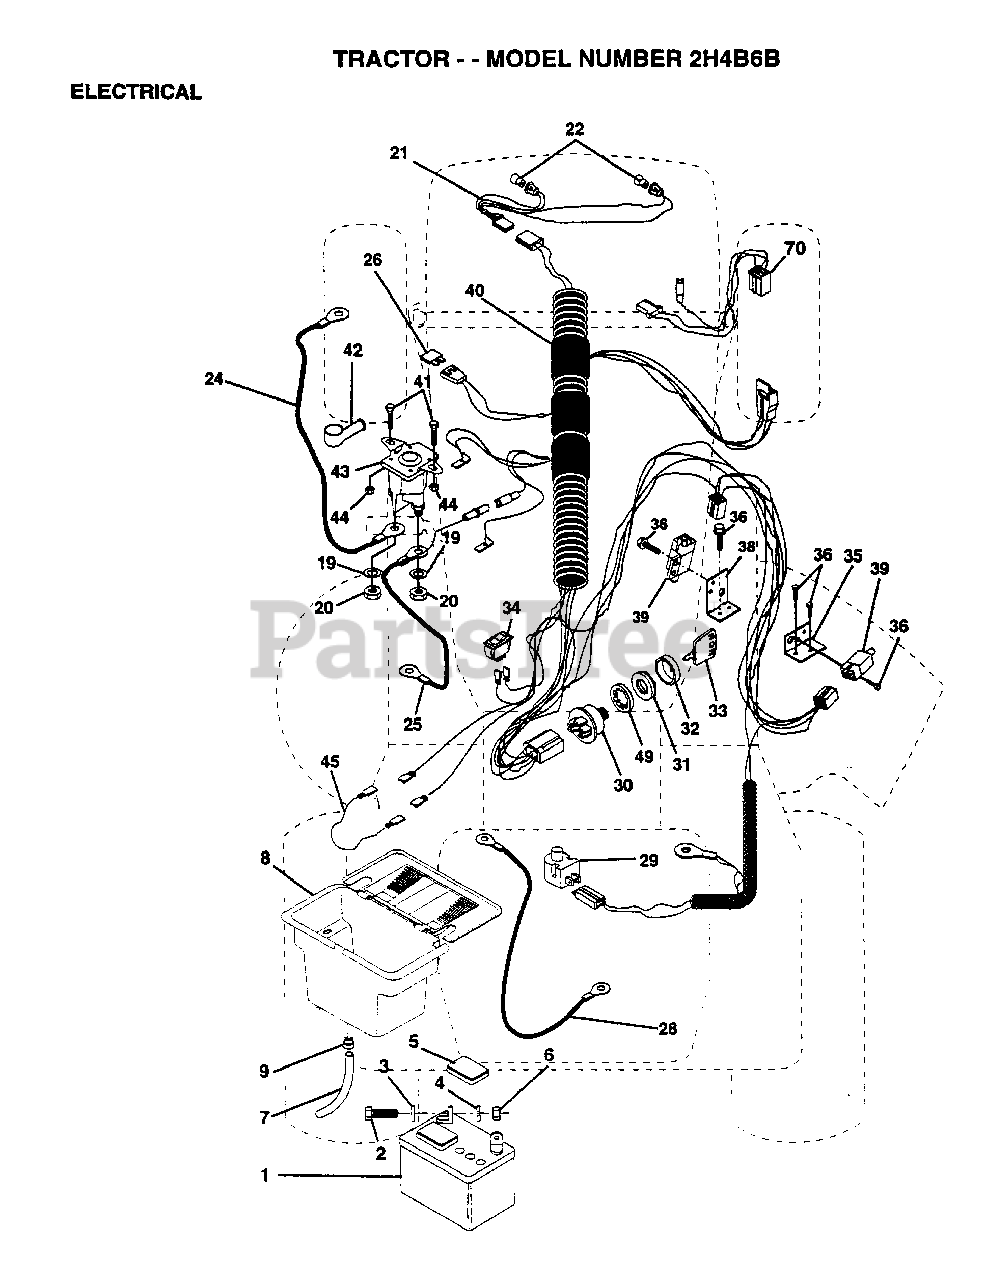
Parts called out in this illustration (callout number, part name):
2	BOLT LT
3	WASHER
4	LOCKWASHER
5	"CAP,BATTERY "
7	TUBE T
9	HOSE CLAMP T
20	NUT
21	"HARNESS,LIGHT SOC"
22	HEADLAMP BULB
24	"CABLE T, BATTERY"
25	CABLE.BTRY.6GA.RD
28	FUSE HYT
28	CABLE T
29	SWITCH SEAT
32	COVER KEY SWITCH
33	KEY MLD GEN DELTA
34	SWITCH LT
35	BRACKET LT
36	SCREW
38	BRACKET SWITCH IN
39	SWITCH INTERLOCKT
40	HARNESS.IGN.DASH.
41	BOLT.HX.1/4-20
44	NUT
45	ADAPTER AMMETER
49	LOCKWASHER
70	HARNESS ENG DUAL
